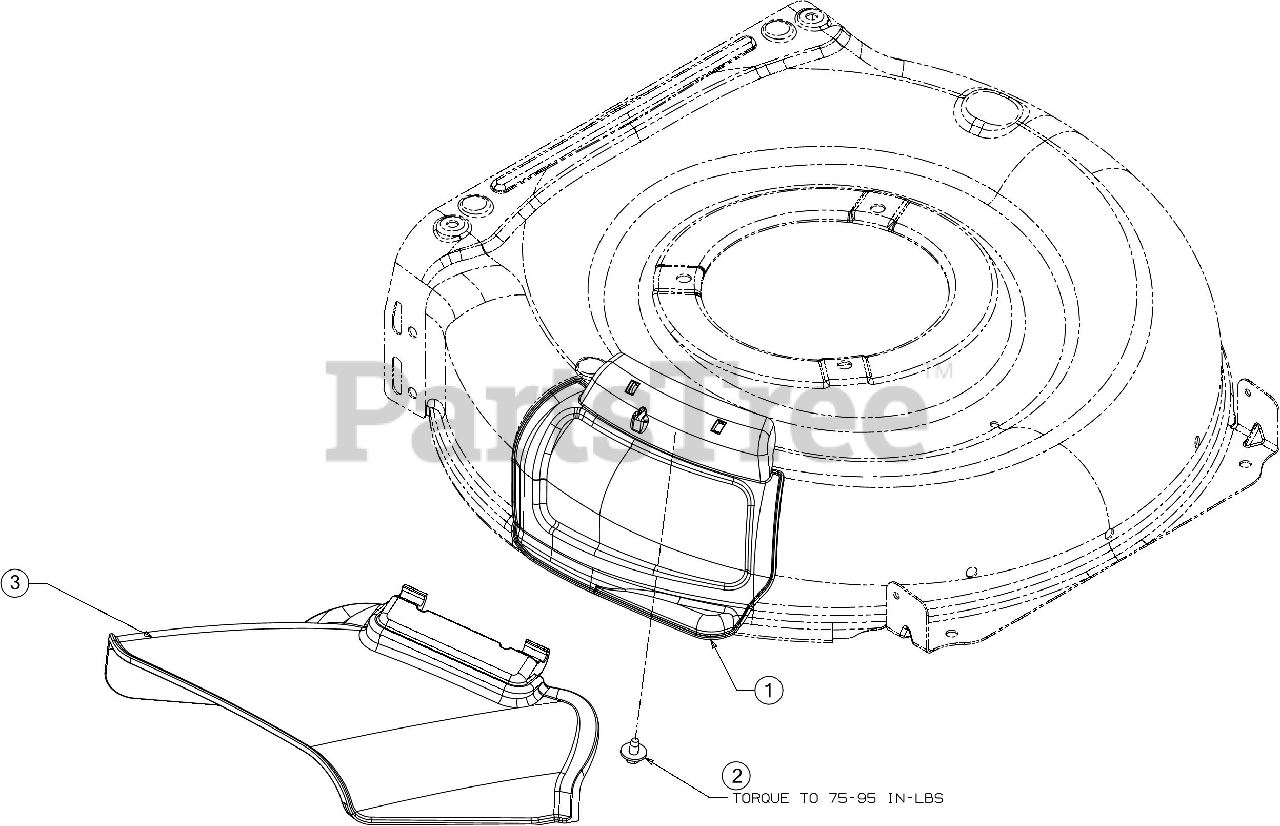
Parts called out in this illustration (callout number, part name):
1	MULCH PLUG ASSEMBLY
2	SCREW 1/4-20 X .50
3	SIDE DISCHARGE CHUTE
